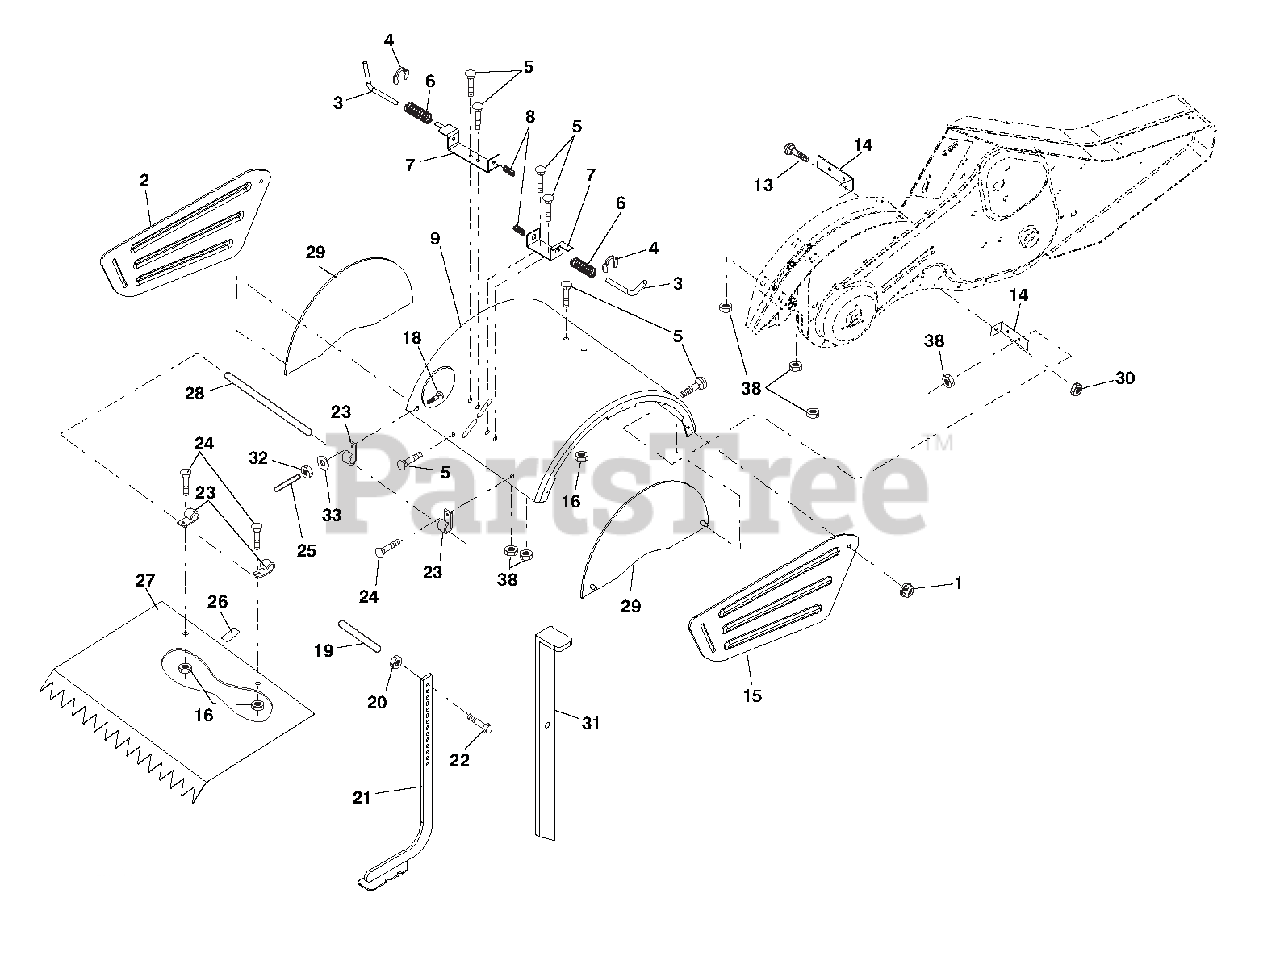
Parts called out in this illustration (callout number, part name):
1	Nut, Lock Hex Flange 5/16-18 u
2	SHIELD, SIDE, OUTER, L.H.
3	Pin, Stake, Depth
4	Ring, Klip
5	Bolt, Carriage, Gr. 5 5/16-18
7	Bracket, Latch
8	Spring, Depth Stake
9	SHIELD, TINE
13	Bolt, Carriage 5/16-18 x 1-1/4
14	Bracket, Shield Tine
15	SHIELD, SIDE, OUTER, RH
16	Nut, Hex Flange 1/4-20 unc
18	Bolt, Carriage 1/4-20 x 1-1/4
20	Nut, Hex 3/8-16
21	Stake, Depth
22	Bolt, Hex 3/8-16 x 2
24	Bolt, Carriage 1/4-20 x 1/2
25	Cap, Vinyl
26	Pad, Idler
27	SHIELD, LEVELING
28	Pin, Hinge
29	SHIELD, SIDE
30	Nut, Hex, Flangelock
31	Stake, Drag
32	Nut, Fin, Hex 1/4-20 unc
33	Washer, Lock 1/4
38	Nut, Keps 5/16-18 unc
